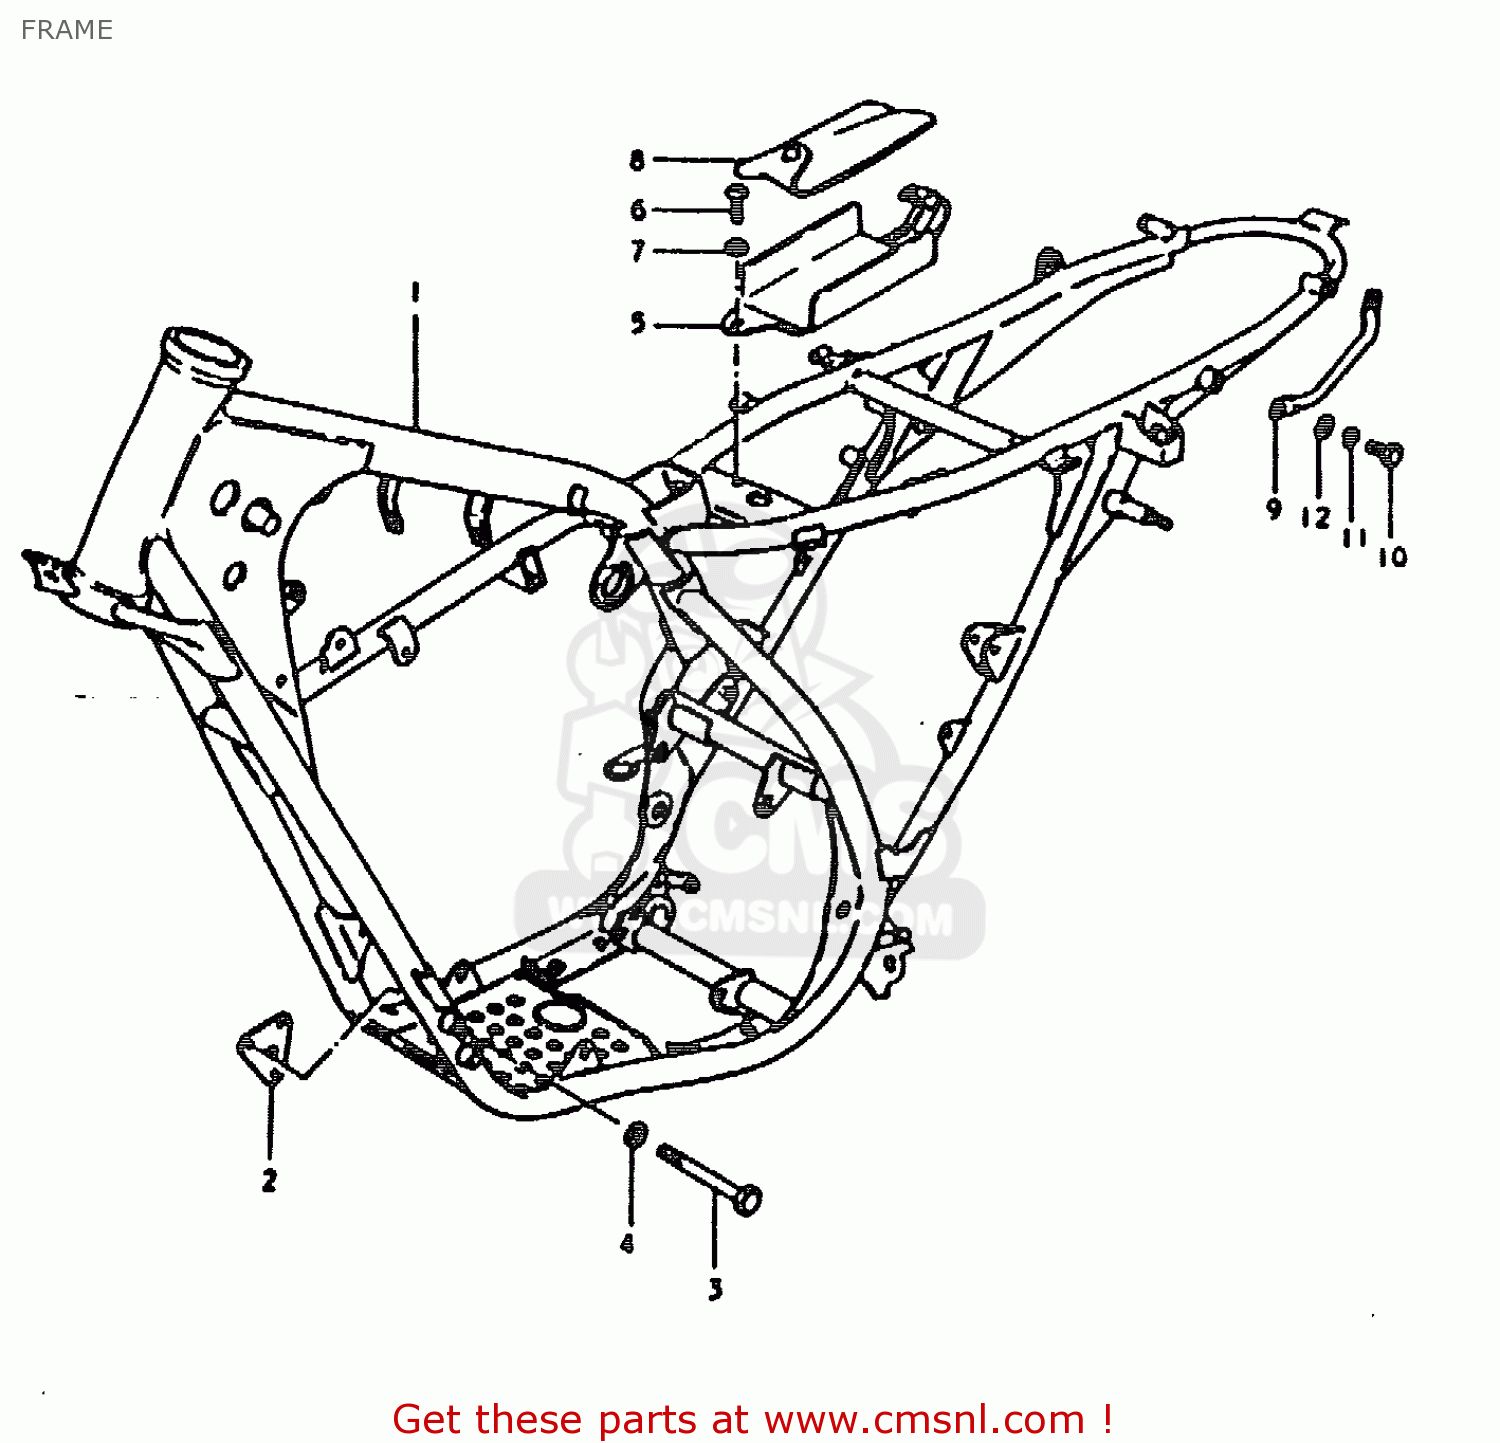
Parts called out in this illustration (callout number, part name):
1	FRAME
2	PLATE,ENG MTG,L
3	BOLT 8X55
4	WASHER
5	HOLDER,TOOL
6	SCREW
7	WASHER
8	TOOL SET
9	GRIP,FRAME HANDLE
10	BOLT
11	LOCK WASHER
12	WASHER
